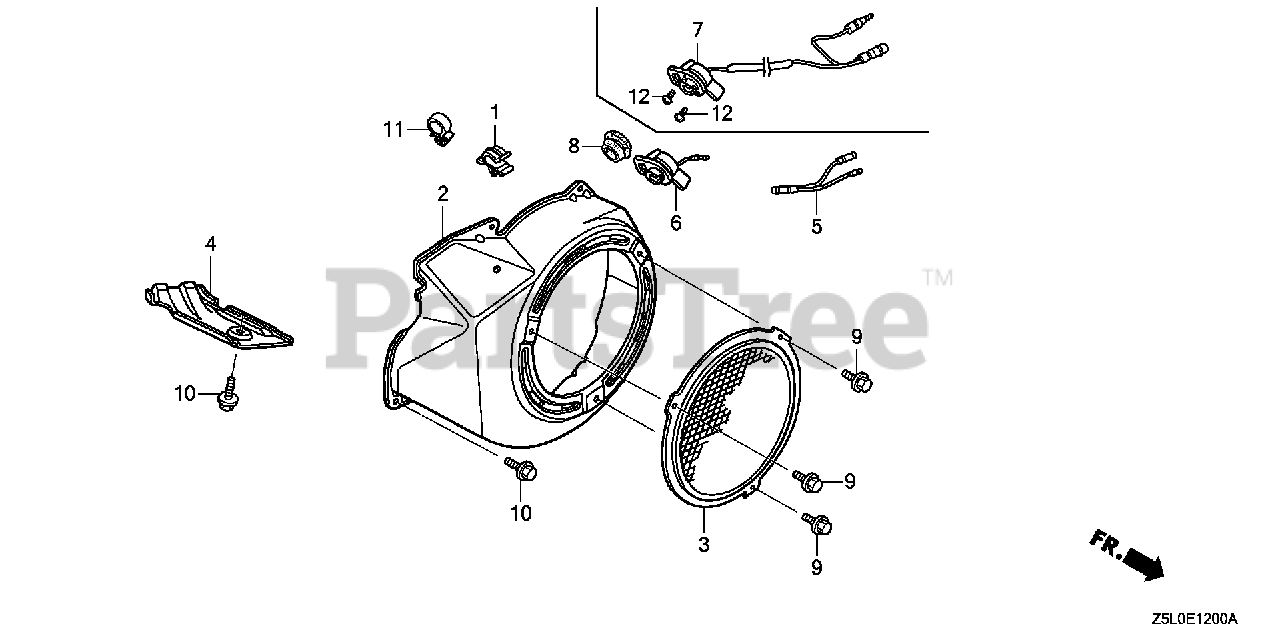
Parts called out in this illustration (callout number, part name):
2	COVER, FAN *NH1* (BLACK)
8	GROMMET, DRAIN HOLE
10	BOLT, FLANGE (6X12) (CT200)
11	CLIP, WIRE HARNESS (6MM) (WHITE)
